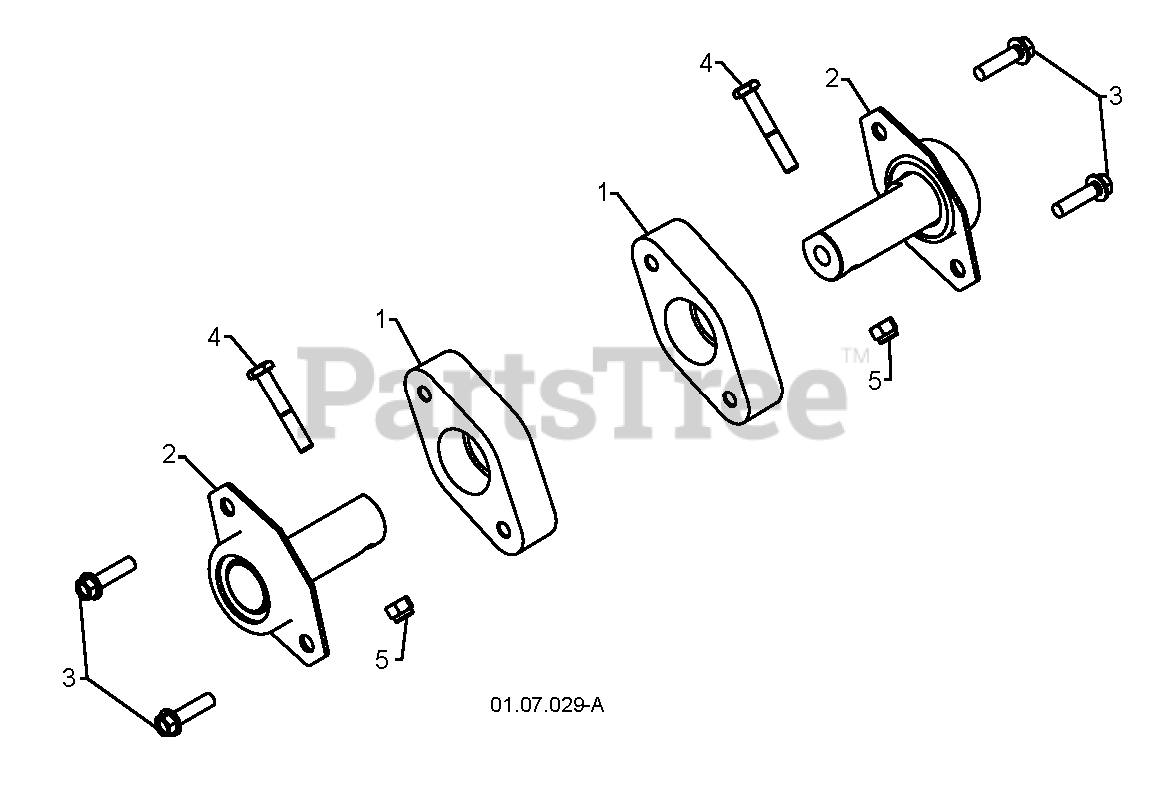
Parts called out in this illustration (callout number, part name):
1	BEARING RETAINER, PLASTIC
2	BEARING.BALL.AUGER.FLAT.
3	SCREW, HEX HD 5/16X1
4	SCREW.HEX.HD1/4-20X
5	LOCKNUT.NYLOC.1/4-20
